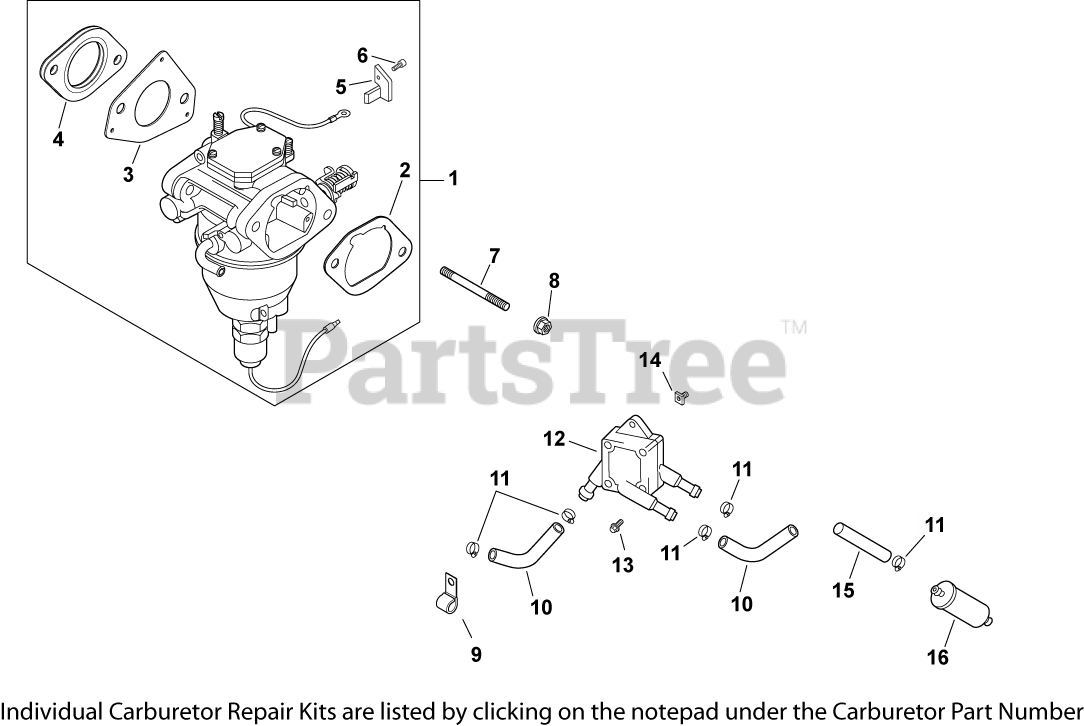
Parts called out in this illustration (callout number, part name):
1	KIT, CARBURETOR W/GASKETS
2	GASKET, AIR CLEANER BASE
3	GASKET, CARBURETOR
4	GASKET, CARBURETOR
5	BRACKET, THROTTLE STOP
6	SCREW, PHL THD FRM M2.5X0.45X5
7	STUD,M6X1.0X96
8	NUT, FLG M6X1.0
9	CLIP, CABLE
10	LINE, FUEL 11"
11	CLAMP, HOSE (KM)-USE 25 237 31-S
12	PUMP, FUEL
13	SCREW, TAP M6X1.7X18
14	NUT, PLASTIC - BLACK
15	LINE, FUEL 10"
16	FILTER,FUEL 51 MICRON (FUEL PUMP)
